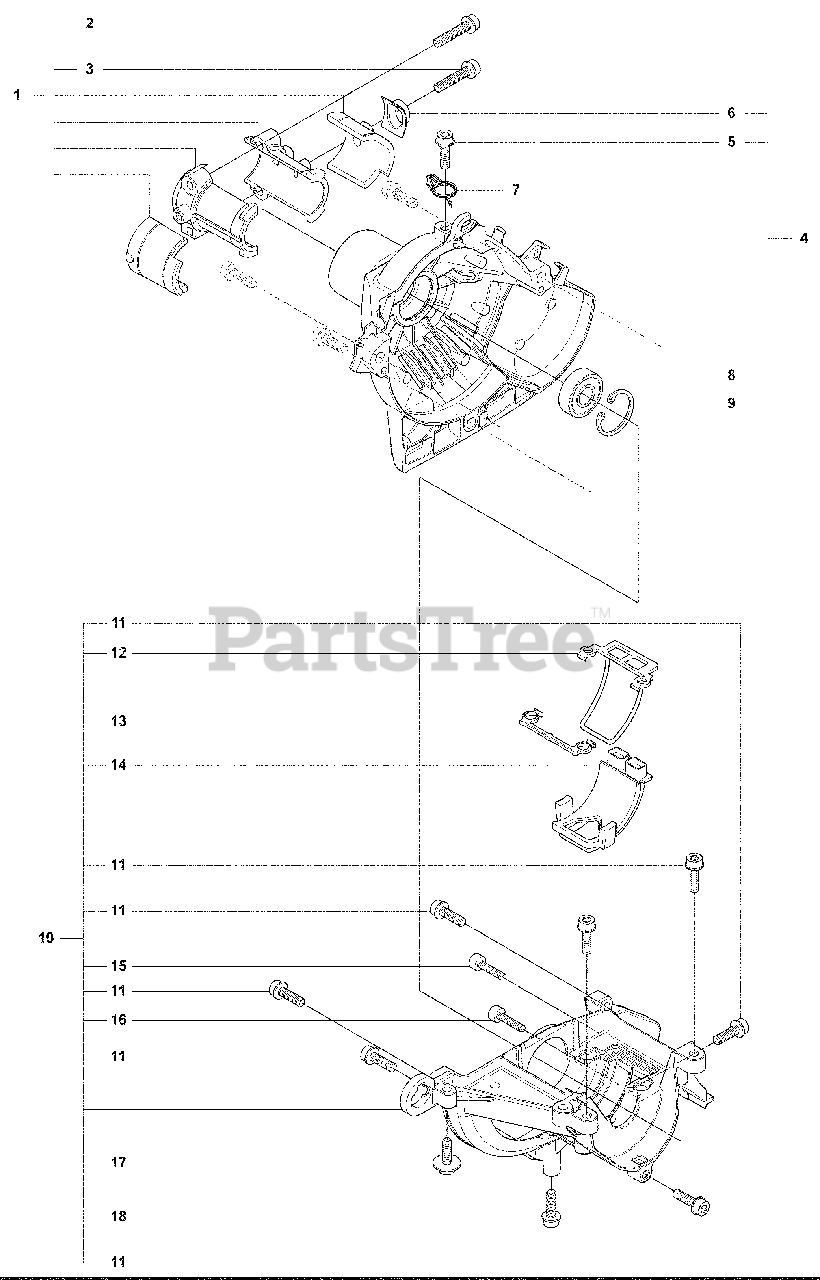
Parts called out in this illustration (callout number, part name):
1	Compresion Sleeve and Isolator Set
4	Clutch Cover
5	Screw
6	Protection Plate
9	Retaining Ring
10	CRANKCASE
18	Screw, M5 X 12 Ms Hcs Ih X
